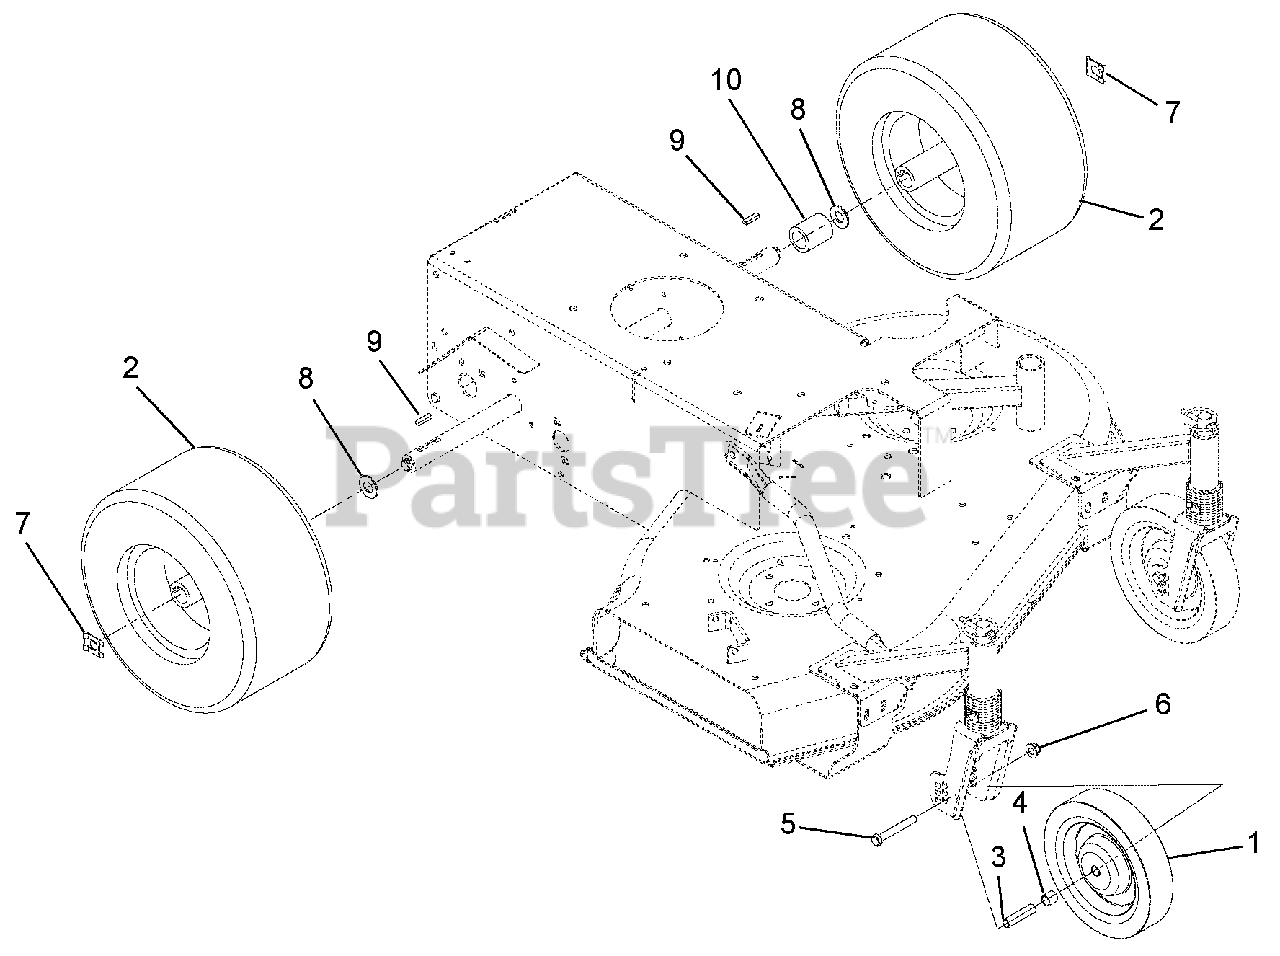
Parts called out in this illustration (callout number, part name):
1	Wheel, 8.0 x 1.75 x .50 - Ball Bearing
2	Assembly, Tire/Wheel 6 x 13
3	Spacer, Wheel
4	Spacer, Wheel
5	Bolt, Hex .38-16 x 2.75
6	Nut, Nyloc Flange .38-16
7	Clip, Snap .625 Diameter
8	Washer, Flat Steel .656 x 1.31 x .095
9	Key, Rectifier .25 x .188 x 1.00
10	Spacer 1.0 x 1.5 x 1.57
